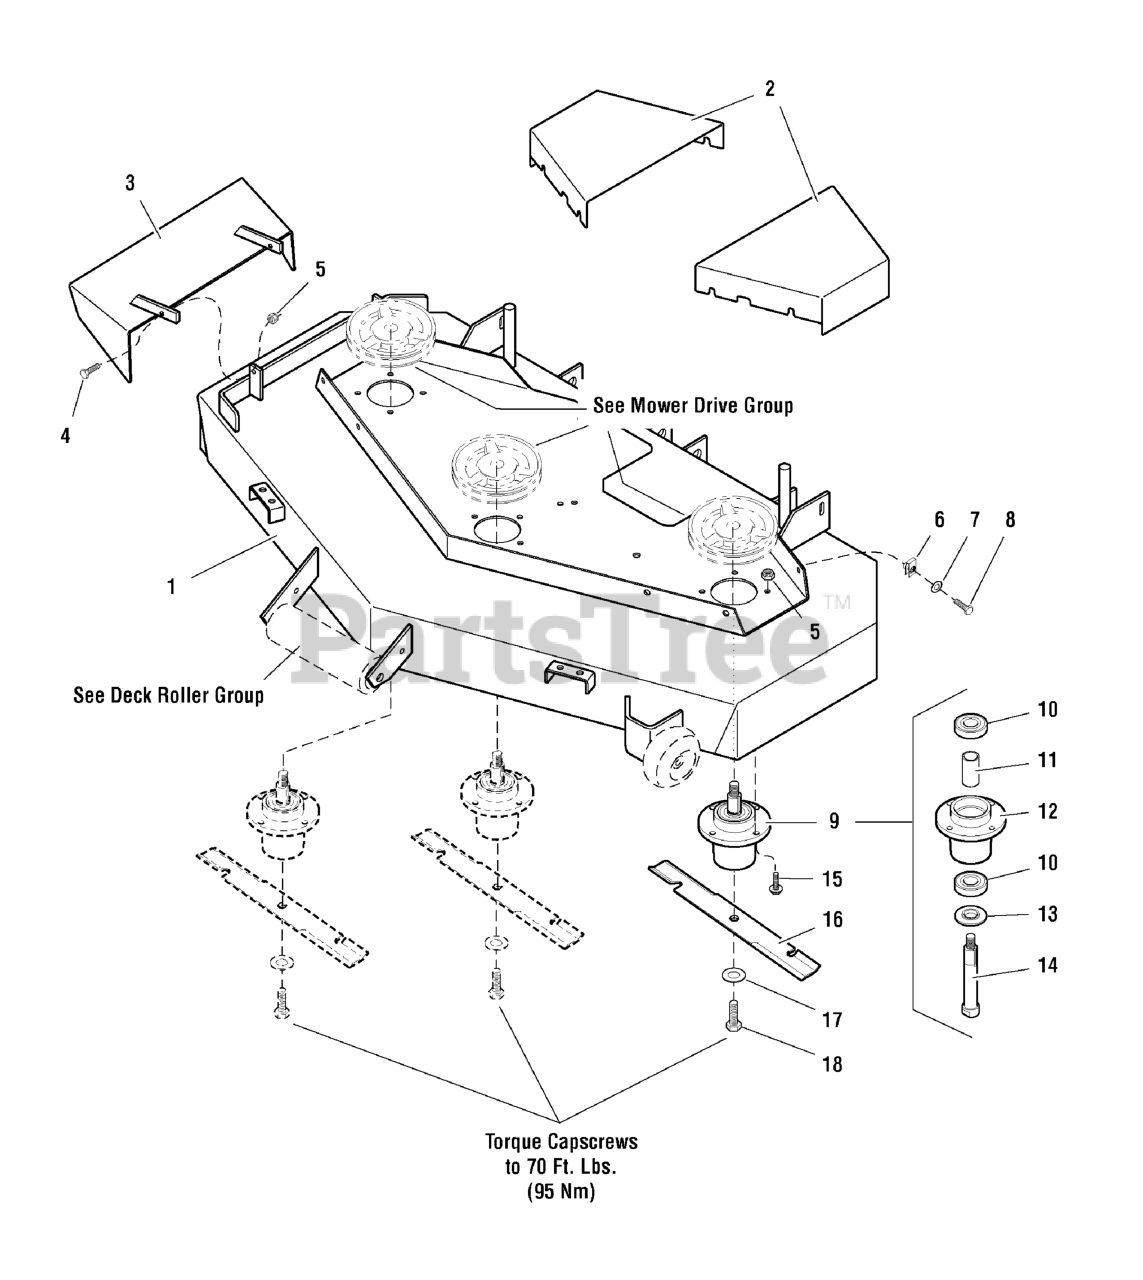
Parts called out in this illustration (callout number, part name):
1	DECK SHELL W/DECALS, 48"
1	DECK SHELL W/DECALS, 52"
2	MOWER HOUSING GUARD
3	DISCHARGE CHUTE
4	BOLT, 5/16-18 X 1" GRD5 YZ
5	NUT, Hex, Nylon Locking, 5/16-18
6	BODY CLIP, 5/16-18-7GA MATERIAL
7	WASHER, 5/16" SAE
8	BOLT, 5/16-18 X 3/4 GD5
9	* SPINDLE ASSEMBLY, Complete
15	BOLT, Flange Head, 5/16-18 x 1-1/4
16	BLADE SET, 48 DECK (SET OF 3 BLADES)
16	BLADE, 18" (SET OF THREE)(SV)
17	WASHER, 5/8" USS
18	BOLT, 5/8-11 X 1-3/4 GD8
